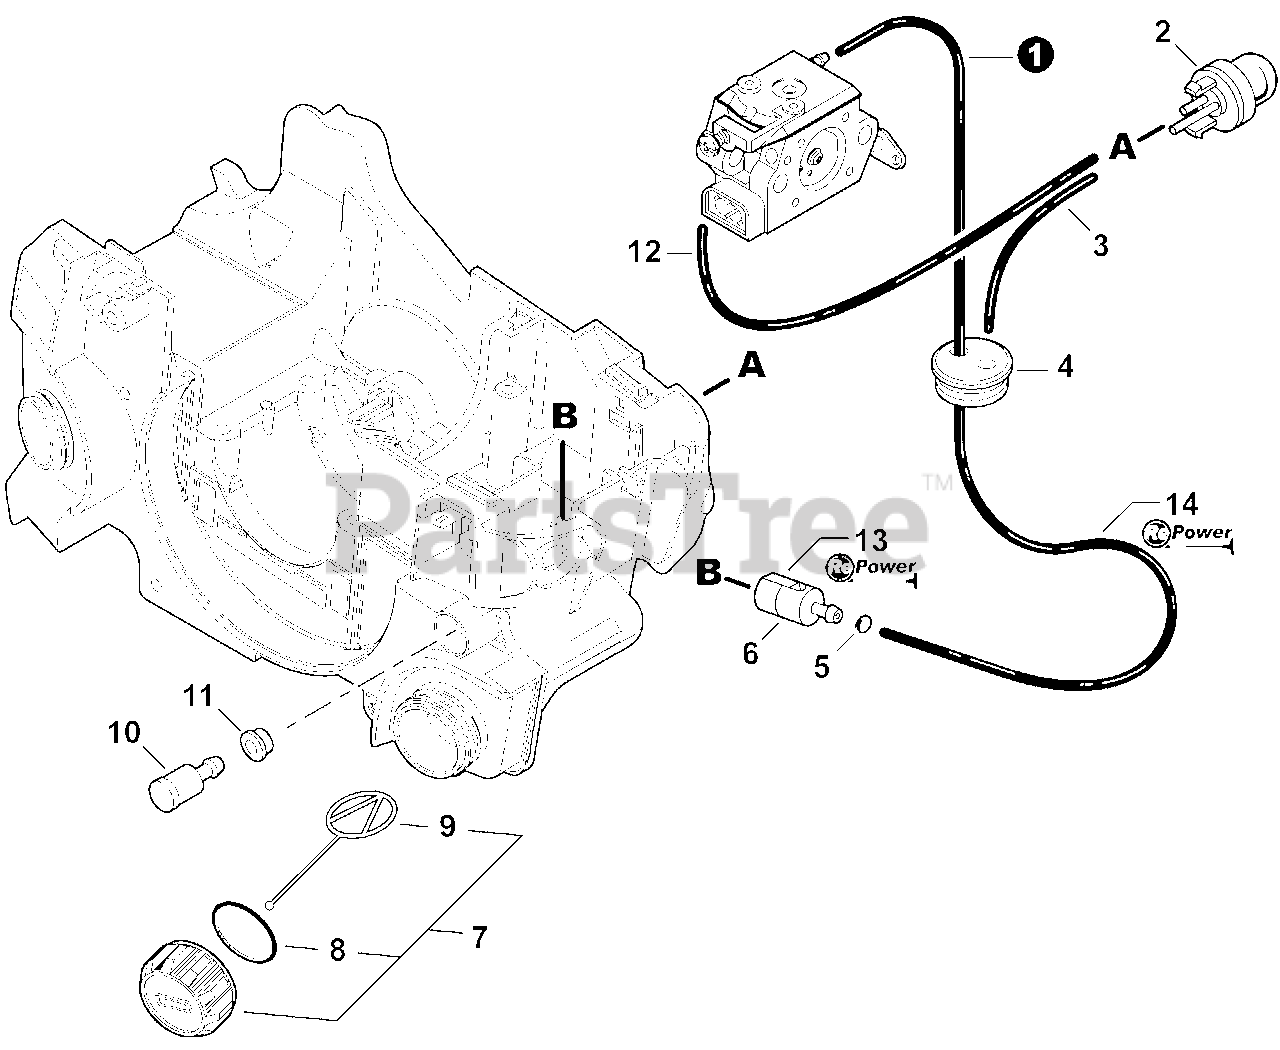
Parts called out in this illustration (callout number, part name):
1	PIPE, FUEL 3×5×230 BLACK
2	BULB, PURGE
3	PIPE, FUEL RETURN 2.4×5×80 BLACK
4	GROMMET, FUEL
5	CLIP 6MM
6	FILTER, FUEL
7	CAP ASSY, FUEL
8	O-RING 22
9	CONNECTOR, CAP L= 60mm
10	VENT ASSY
11	GROMMET, FUEL
12	PIPE 2.4×5×125 BLACK
13	TUNE-UP KIT - REPOWER
14	PIPE, FUEL - REPOWER BULK 3×5mm BLACK
